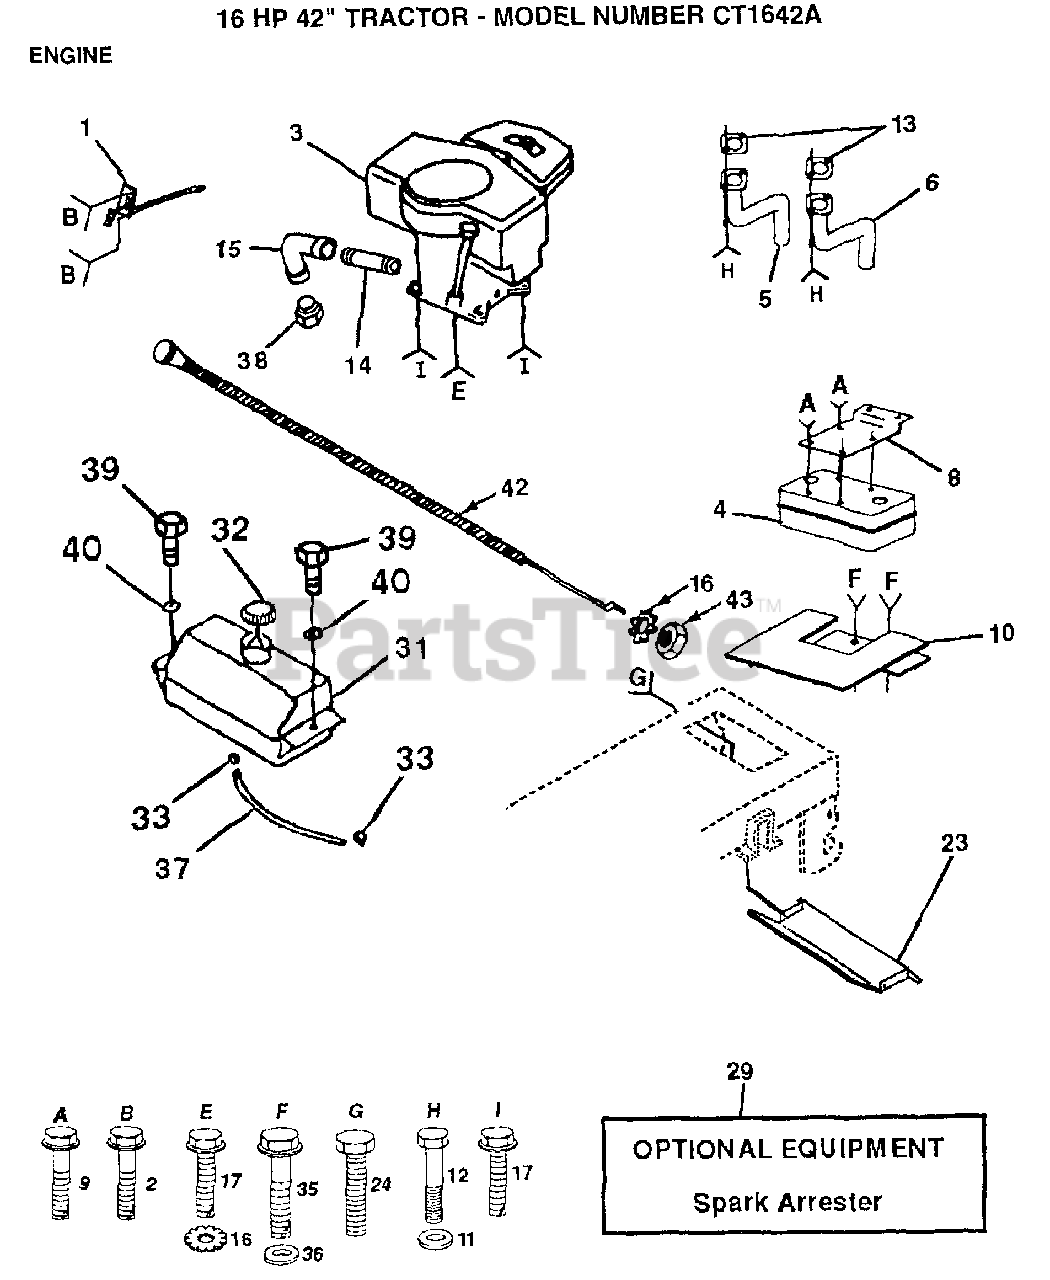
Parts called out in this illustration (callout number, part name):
1	CONTROL.THR.33.
2	SCREW LT
3	ENGINE, B&S
5	EXHAUST ASM LH
8	BRACKET MUFFLER
9	SCREW ST
10	SHIELD HEAT LT
11	LOCKWASHER
14	PIPE NIPPLE LT
15	ELBOW
16	LOCKWASHER
17	SCREW
23	HEAT SHIELD
24	SCREW
32	CAP ASM FUEL
33	HOSE CLAMP
35	SCREW
36	WASHER
37	LINE FUEL
39	SCREW HEX CRT
40	WASHER
